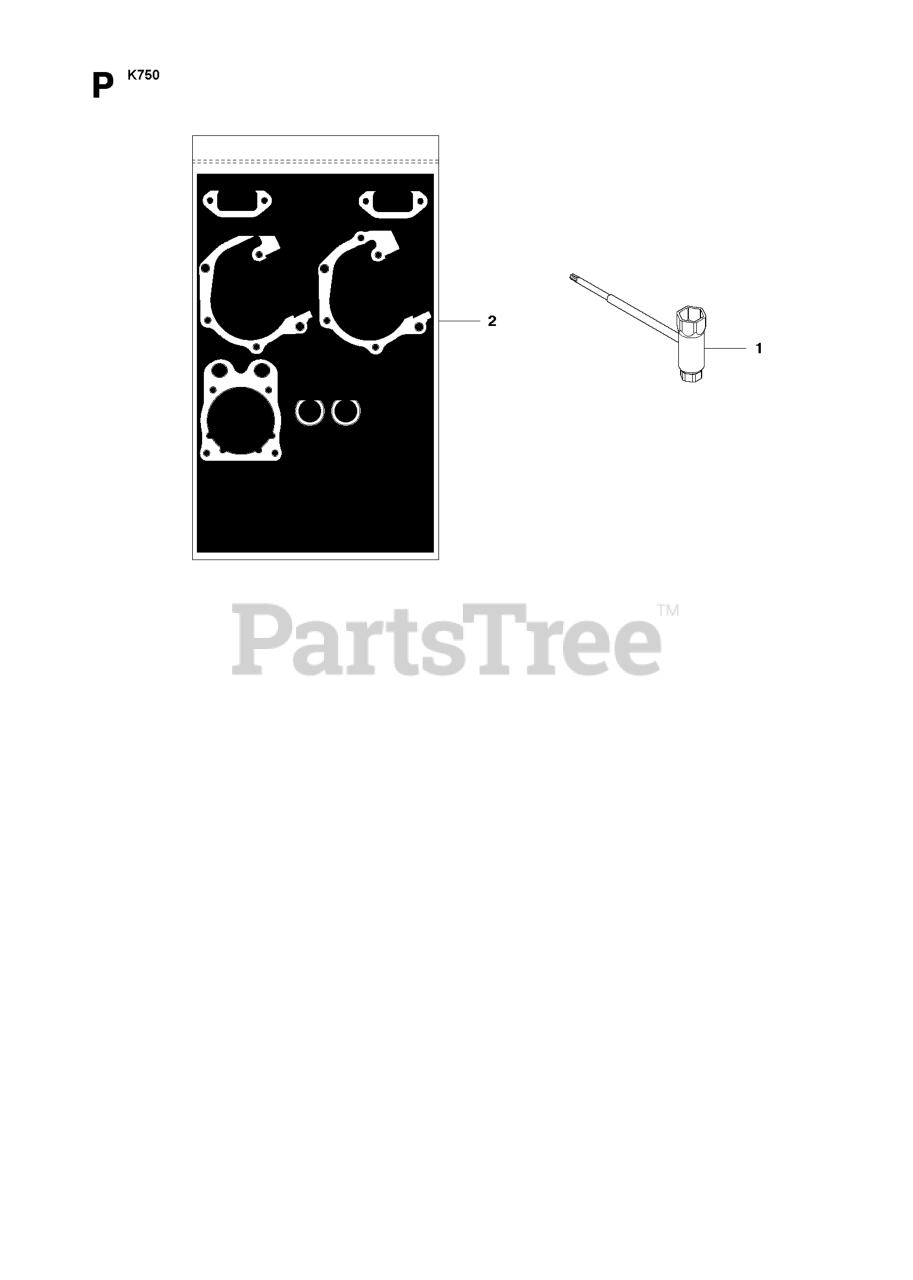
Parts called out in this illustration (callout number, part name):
2	GASKET KIT
4	GASKET
8	SEALING RING
10	RP GASKET CARBURETOR
